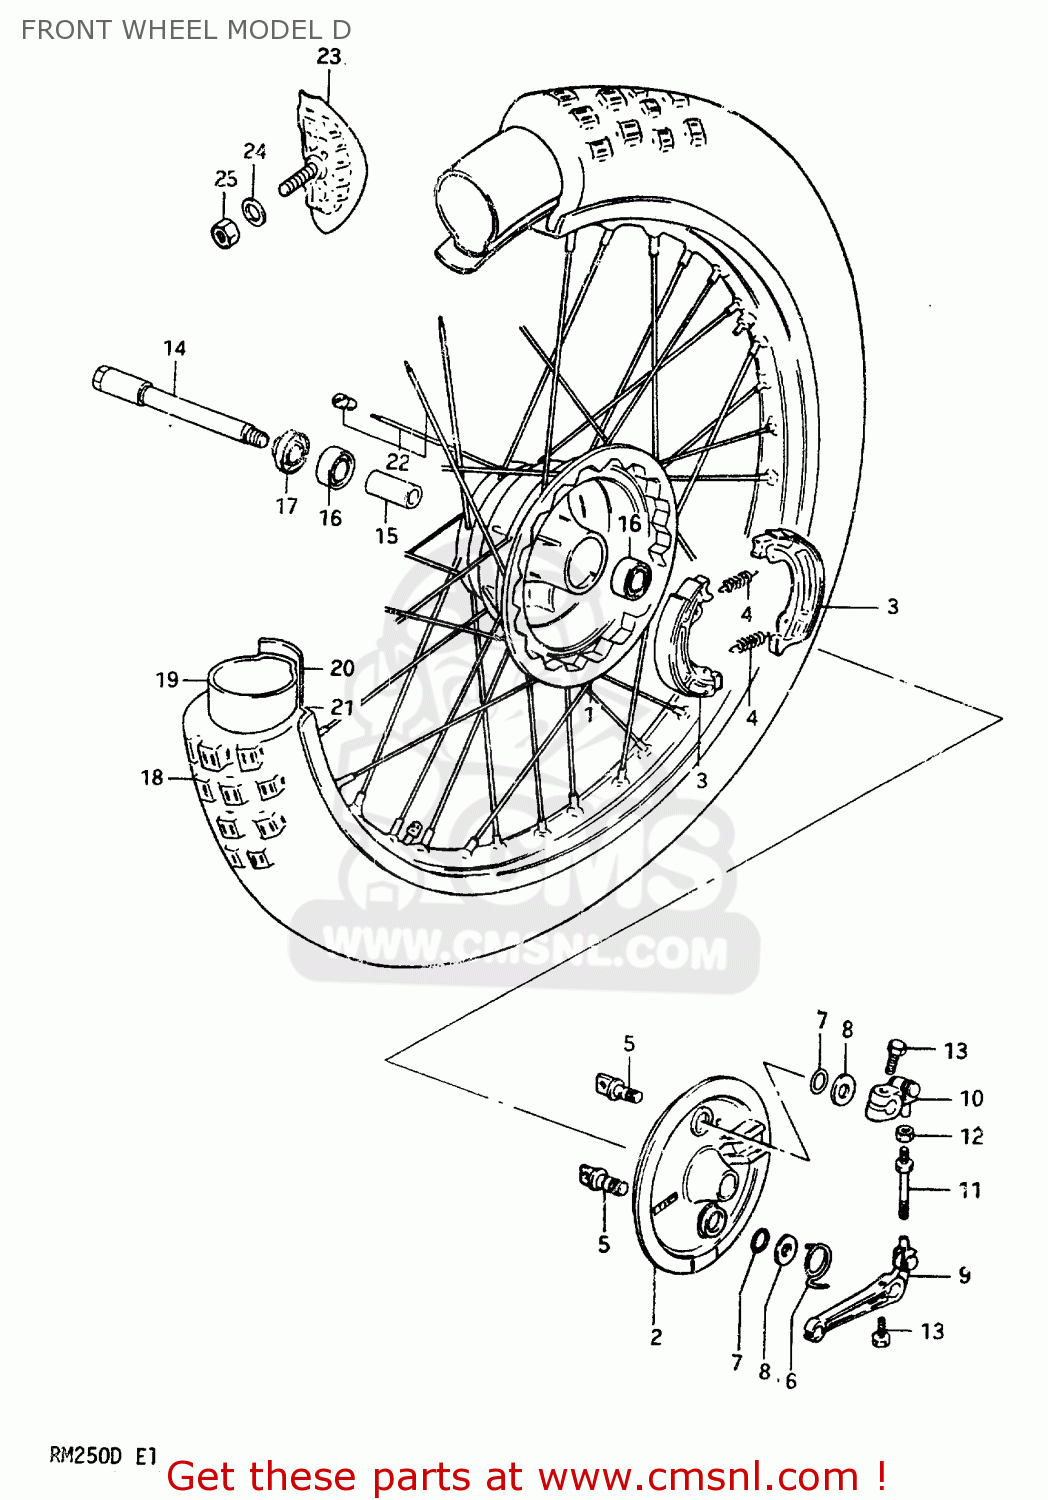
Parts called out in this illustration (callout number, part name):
1	DRUM,FRONT HUB
2	PANEL,FRONT HUB
3	SHOE,BRAKE (MCA)
4	SPRING
5	CAM,FRONT BRAKE
6	SPRING
7	O-RING (D:2 ID13.8)
8	WASHER (14.2X22X1)
9	LEVER, BRAKE CAM
10	LEVER ASSY, BRAKE CAM, NO.2
11	ROD,BRAKE CAM LEVER CONNECTION
12	NUT 6MM
13	BOLT
14	AXLE,FRONT
15	SPACER,FRONT HUB BEARING
16	BEARING
17	SPACER,FRONT AXLE,RIGHT
18	TIRE,FRONT
19	TUBE
20	PROTECTOR,WHEEL,INNER
21	RIM,FRONT WHEEL (1.60X21)
22	SPOKE SET,FRONT
23	STOPPER,BEAD
24	WASHER
25	NUT
